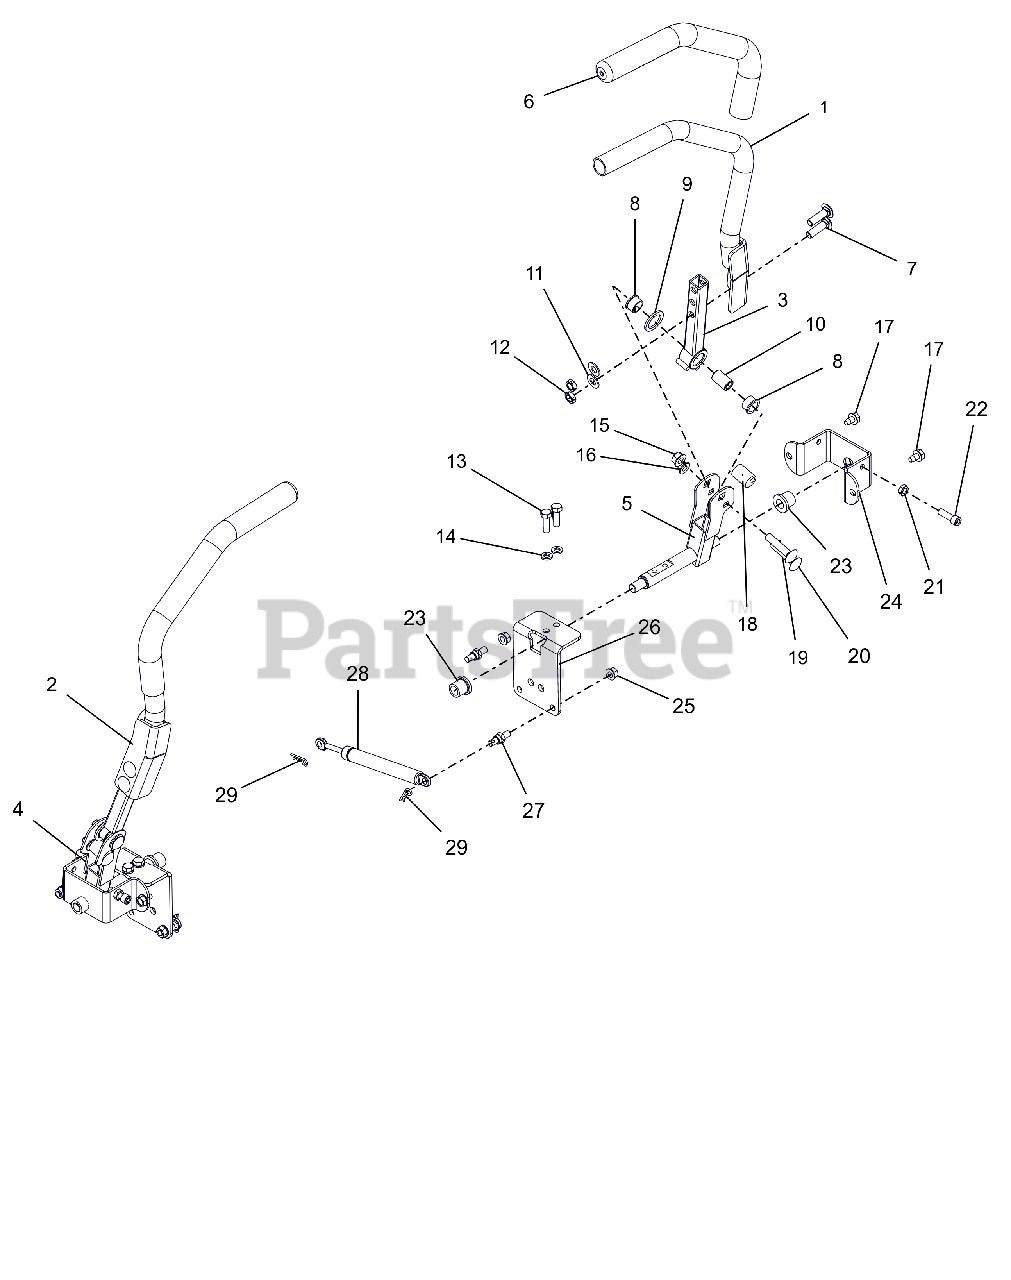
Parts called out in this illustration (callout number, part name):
1	WLDMT, STEERING HANDLE LH
2	WLDMT, STEERING HANDLE RH
3	WLDMT, UPPER CONTROL ARM
4	WLDMT,STEERING ARM LOWER RIGHT
5	WLDMT,STEERING ARM LOWER LEFT
6	GRIP, HANDLEBAR 15" FOAM
7	BLT,RHSSN .38-16X1.25 G5 BFP
8	BSHG-FLG, .625X.75X.450X.875
9	WASHER, FRICTION .875X1.25X.10
10	SPACER, .375X.625X.970 (PM)
11	WSHR,FLT .406X.812X.065 ZCC
12	@NUT-LK-CTR-JAM .375-16 YWZC
13	BLT, HEX .31-18X1.00 G8 ZCC
14	WSHR,LK-REG .312X.078 ZCC
15	NUT-LK-CTR-FLG .375-16 GF ZCC
16	NUT,LK-NYL-FLG .31-18 G5ZC120
17	SCR,TAP .312-18X.50 HWH TR ZCC
18	BSHG,ECCEN .328X.750X1.01 PM
19	BLT,RHSSN .38-16X1.75 G5 BFP
20	BLT,RHSSN .31-18X1.75 G5 BFP
21	NUT-JAM .312-18 G2 ZCC
22	SCR, SKH .312-18X1.00 G8 SS
23	BSHG-FLG .515X.750X.745X1.00NY
24	BRKT, STEERING
25	NUT-LK-TOP-FLG .312-18 GF ZCC
26	BRKT, STEEERING
27	COUPLER, DAMPER MOUNT
28	DAMPER, STRAIGHT MOUNT
29	PIN, HAIR #213 .08X1.19 ZCC
